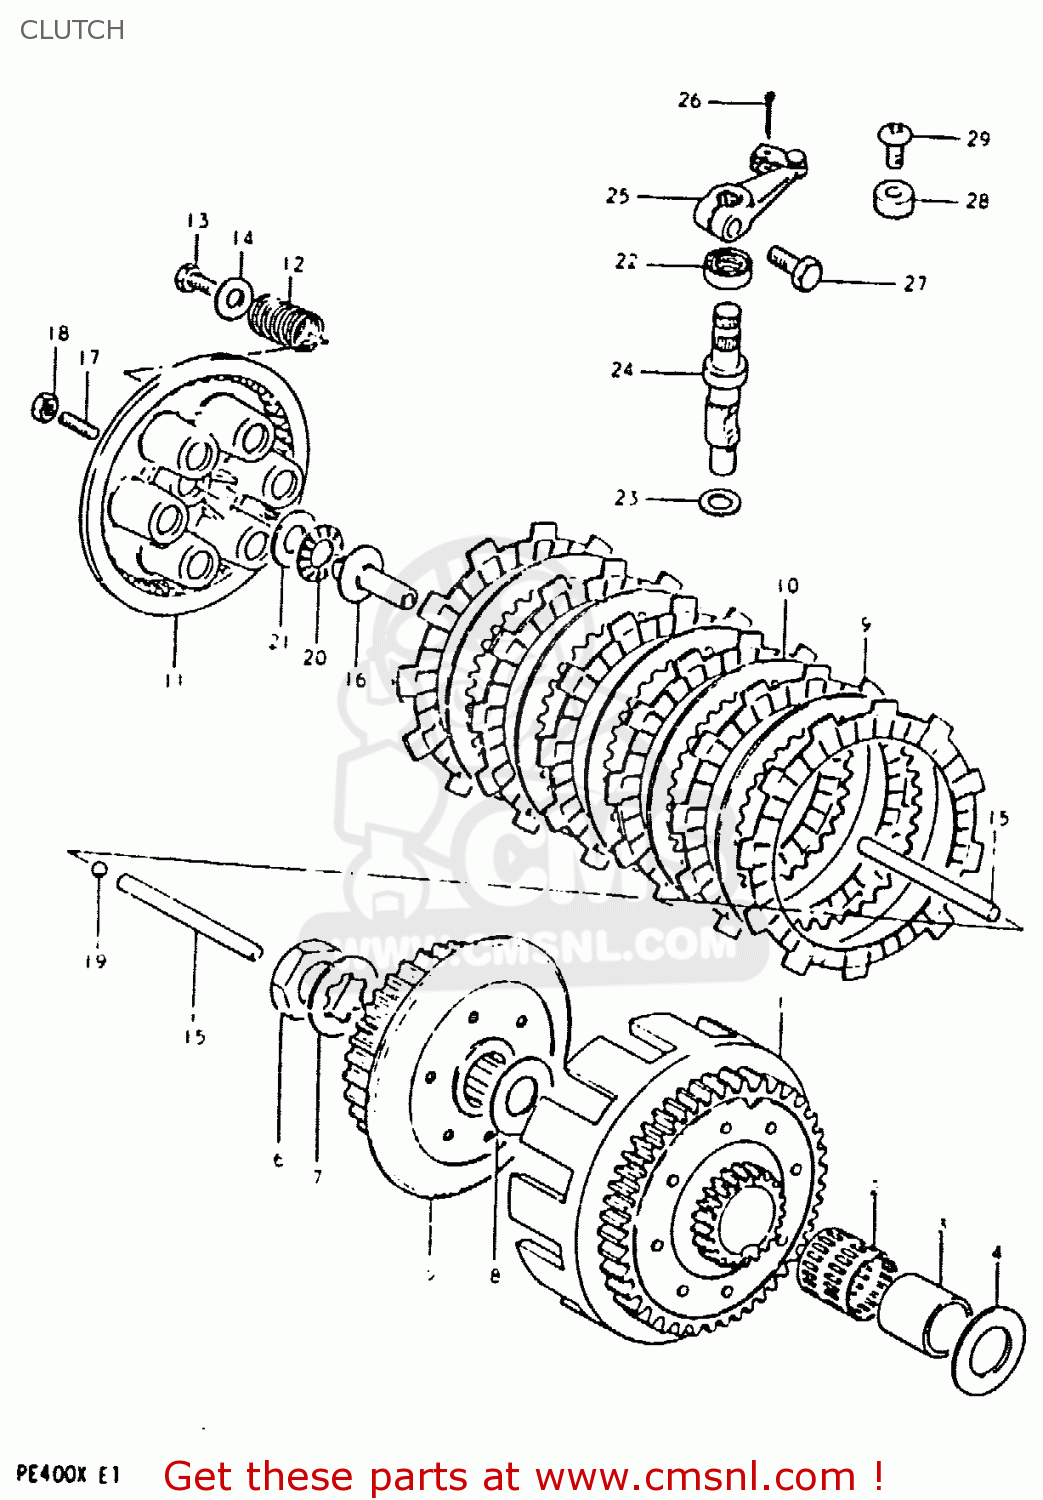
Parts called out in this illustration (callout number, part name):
1	GEAR ASSEMBLY,PRIMARY DRIVE
2	ROLLER BEARING (25X30X2
3	SPACER
4	WASHER(20X38X2)
5	HUB,CLUTCH SLEEVE
6	NUT (20MM)
7	WASHER,LOCK
8	WASHER(20X38X2)
9	PLATE,CLUTCH DRIVE (MCA)
10	PLATE,CLUTCH DRIVEN (NAS)
11	DISC,CLUTCH PRESSURE
12	SPRING
13	BOLT, UPPER
14	WASHER
15	ROD,CLUTCH PUSH
16	PIECE,CLUTCH PUSH
17	SCREW
18	NUT 6MM
19	BALL
20	BEARING(15X28X2)
21	WASHER
22	OIL SEAL
23	WASHER (14.2X22X1)
24	SHAFT,CLUTCH RELEASE C
25	ARM,CLUTCH RELEASE
26	PIN
27	BOLT
28	GUIDE,CLUTCH CABLE
29	SCREW
